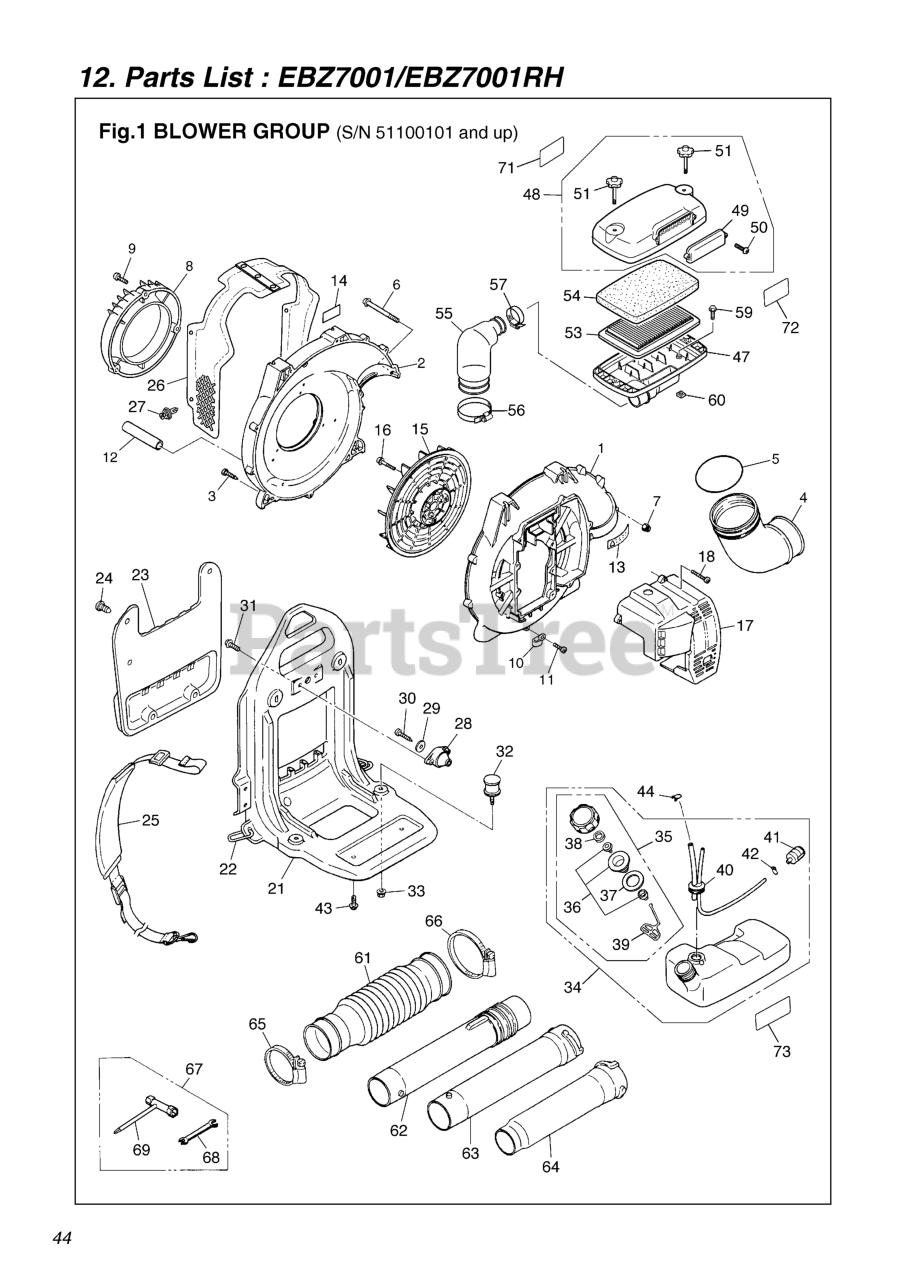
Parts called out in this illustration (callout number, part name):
1	VOLUTE CASE
2	VOLUTE COVER
3	SCREW
4	ELBOW
5	O-RING
6	SCREW TORX
7	NUT (B)
8	COVER, INLET
9	SCREW
10	CLAMP (RPLS 1140-72231)
12	TUBE (RPLS. 07270-01507)
13	LABEL, CAUTION (RPLS -31910)
14	LABEL, NET
15	FAN
16	BOLT
17	ENGINE COVER
18	SCREW
21	FRAME COMP
22	RING (REPLACES -21120)
23	PAD
24	CLIP (RPLS 3490-21320)
25	BAND ASSY (RPLS 2750- )
26	NET COMPLETE
27	CLIP
28	DAMPER, UPPER
29	WASHER
30	BOLT, TORX
31	SCREW TORX
32	DAMPER, LOWER
33	NUT, M6
34	TANK ASSY (RPLS. -85100)
35	CAP ASSY (RPLS -85201)
36	HOLDER (REPLACES -85230)
37	PACKING
38	FILTER
39	STOPPER
40	PIPE COMPLETE
41	FILTER ASSY
42	CLIP (REPLACES 2841-31280)
43	SCREW TORX
44	CLIP
47	BODY (RPLS. T4012-82111)
48	COVER ASSY
49	COVER
50	SCREW
51	KNOB BOLT
53	ELEMENT (PAPER)
54	ELEMENT (FOAM) (RPLS -82320)
55	HOSE
56	CLAMP
57	CLAMP
59	BOLT (USE 848-815-2000)
60	NUT
61	FLEX HOSE
62	SWIVEL JOINT
63	PIPE, STRAIGHT
64	PIPE, END
65	CLAMP
66	CLAMP
67	TOOL-SET
68	SPANNER, 8 X 10 (RPLS 2540- )
71	LABEL
72	LABEL, EBZ7001
